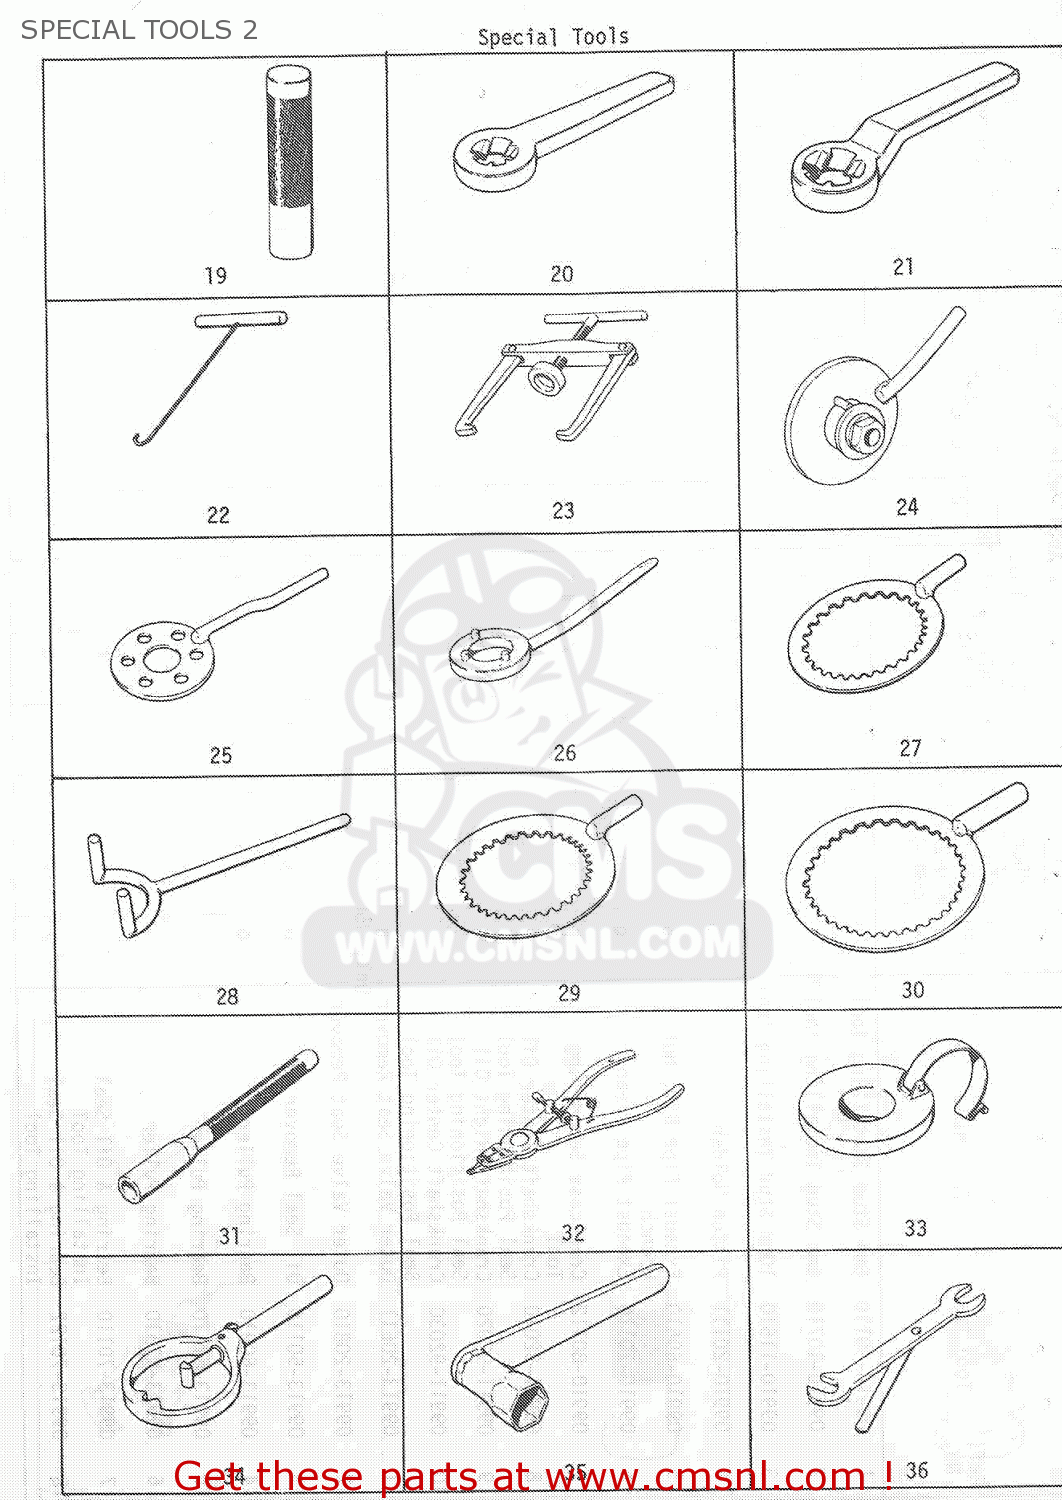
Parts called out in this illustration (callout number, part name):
28	CLUTCH SLEEVE HUB HOLDER
32	SNAP RING OPENER
34	ENGINE SPROCKET HOLDER
35	SPARK PLUG WRENCH
36	WRENCH, CONTACT POINT
